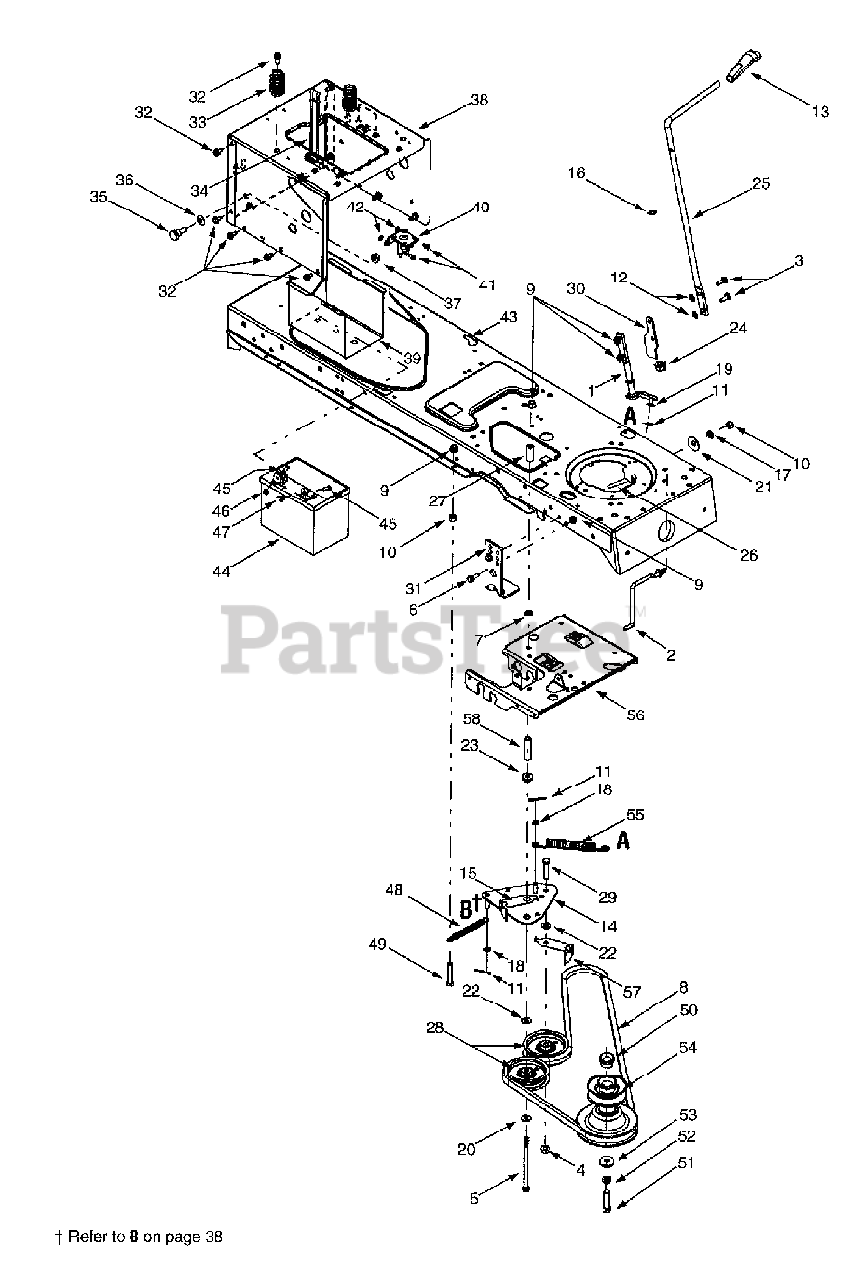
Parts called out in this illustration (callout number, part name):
1	PTO Engagement Lever Assembly
2	Belt Keeper Rod
3	Carriage Screw, 5/16-18 x 1.00
4	Flange Lock Nut, 3/8-16
5	Hex Cap Screw, 3/8-16 x 5.5
6	Hex Head Washer Screw, 5/16-18 x .875
7	Push Nut, 3/8
8	PTO Belt
9	Flange Lock Nut, 5/16-18
10	Hex Nut, 5/16-18
11	Cotter Pin, 1/8 x 1.25
12	Speed Nut, .3125
13	PTO Knob
14	PTO Engagement Plate Assembly
15	Belt Guard
16	Flat Washer, .510 x .750 x .033
17	Lock Washer, 5/16
18	Flat Washer, .385 x .62 x .063
19	Flat Washer, 5/16
20	Flat Washer, .406 x .875 x .059
21	Bell Washer, .39 x 1.13 x .062
22	Flat Washer, .407 x .812 x .135
23	Shoulder Spacer, .380
24	Hex Split Flange Bearing, .b
26	Belt Keeper Rod
27	Spacer, 3/8 x 1.54
28	Idler Pulley, 3.5
29	Hex Cap Screw, 3/8-16 x 1.75
32	Self Tapping Screw, 5/16-18 x .625
33	Compression Spring, 1.28 x 3.5
34	Battery Strap
35	Shoulder Screw, .625 x .5, 7/16-20
36	Bell Washer, .45 x 1.0 x .062
37	Flange Lock Nut, 7/16-20
41	Self Tapping Screw, 1/4-20 x.5
42	Lock Washer, 1/4
45	Hex Cap Screw, 1/4-20 x .62
46	Hex Sems Nut, 1/4-20
47	Wing Nut, 1/4-20
48	Extension Spring, .50 x 5.0
49	Hex Cap. Screw, 5/16-18 x 1.75
50	Spacer Cup
51	Hex Head Cap Screw, 7/16-20 x 1.25
52	Lock Washer, 7/16
53	Flat Washer, .450 x 1.25
54	Engine Pulley, 3.56 OD x 5.56
55	Extension Spring, .75 x 6.75
57	Belt Guard
58	Spacer, .375 x 2.5
